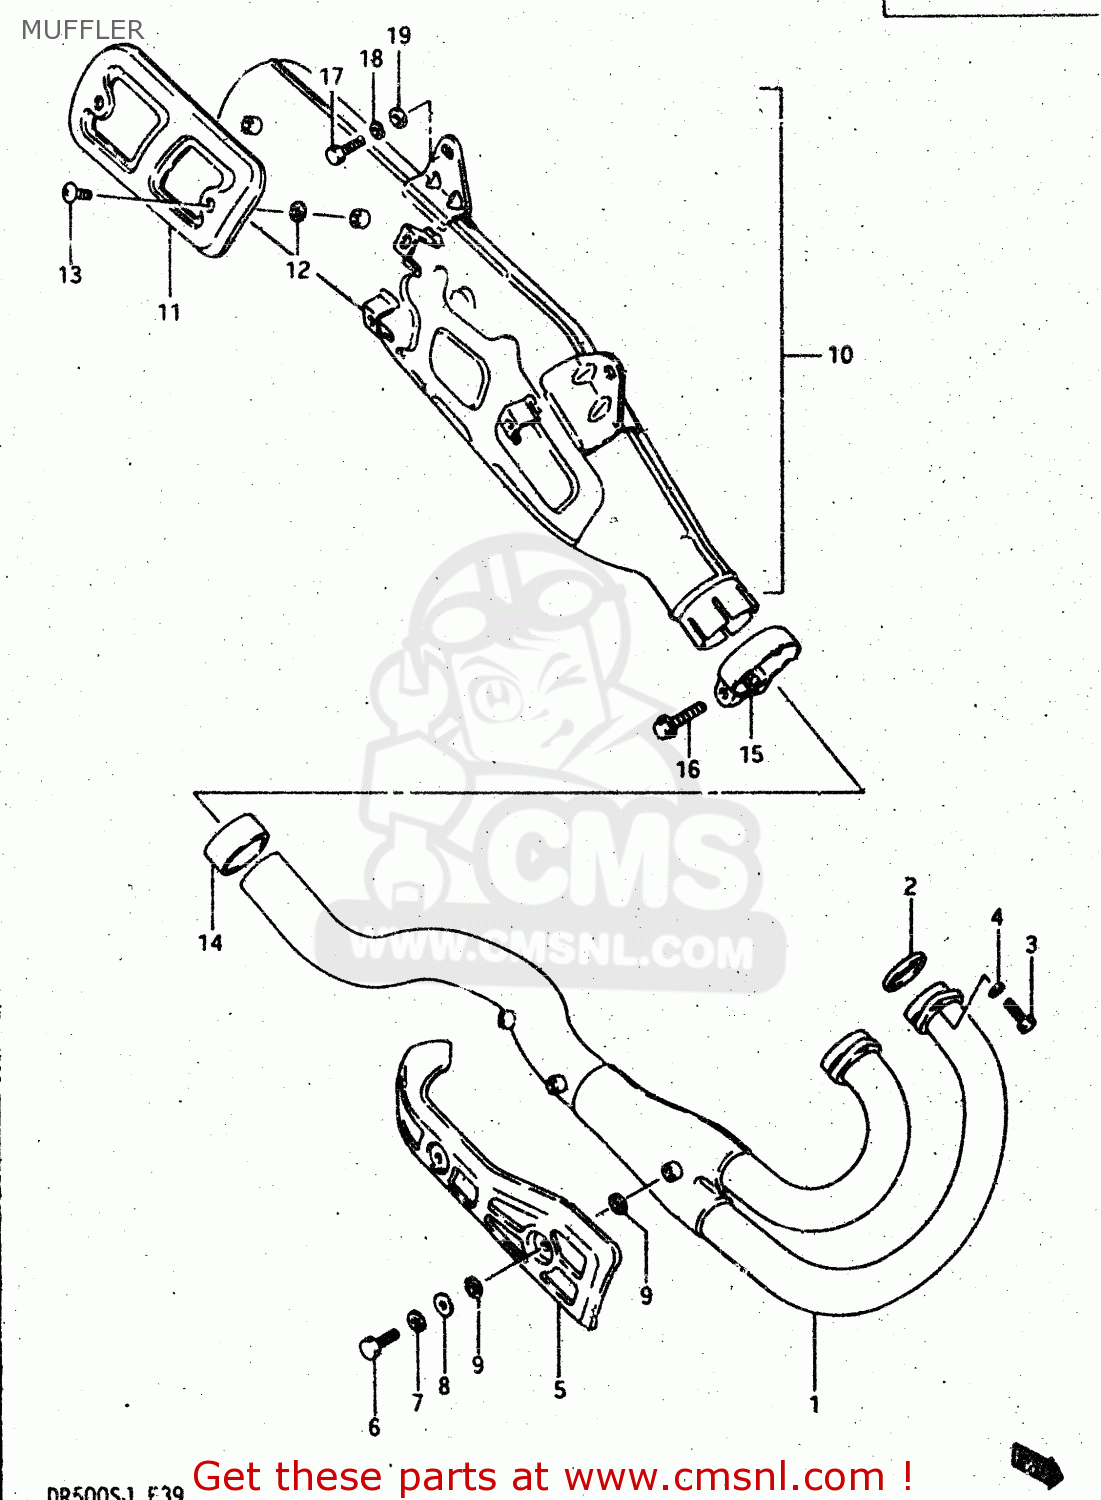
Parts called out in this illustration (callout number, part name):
1	PIPE,EXHAUST
2	GASKET,EXHAUST PIPE
3	BOLT
4	WASHER,LOCK
5	COVER,EXHAUST PIPE
6	BOLT
7	WASHER,LOCK
8	WASHER
9	GASKET
10	MUFFLER ASSY
11	COVER,MUFFLER
12	GASKET,EXHAUST PIPE (MCA)
13	SCREW
14	CONNECTOR,MUFFLER
15	CLAMP,MUFFLER,R(L:42.7)
16	BOLT 8X40
17	BOLT
18	WASHER,LOCK,8.
19	WASHER
